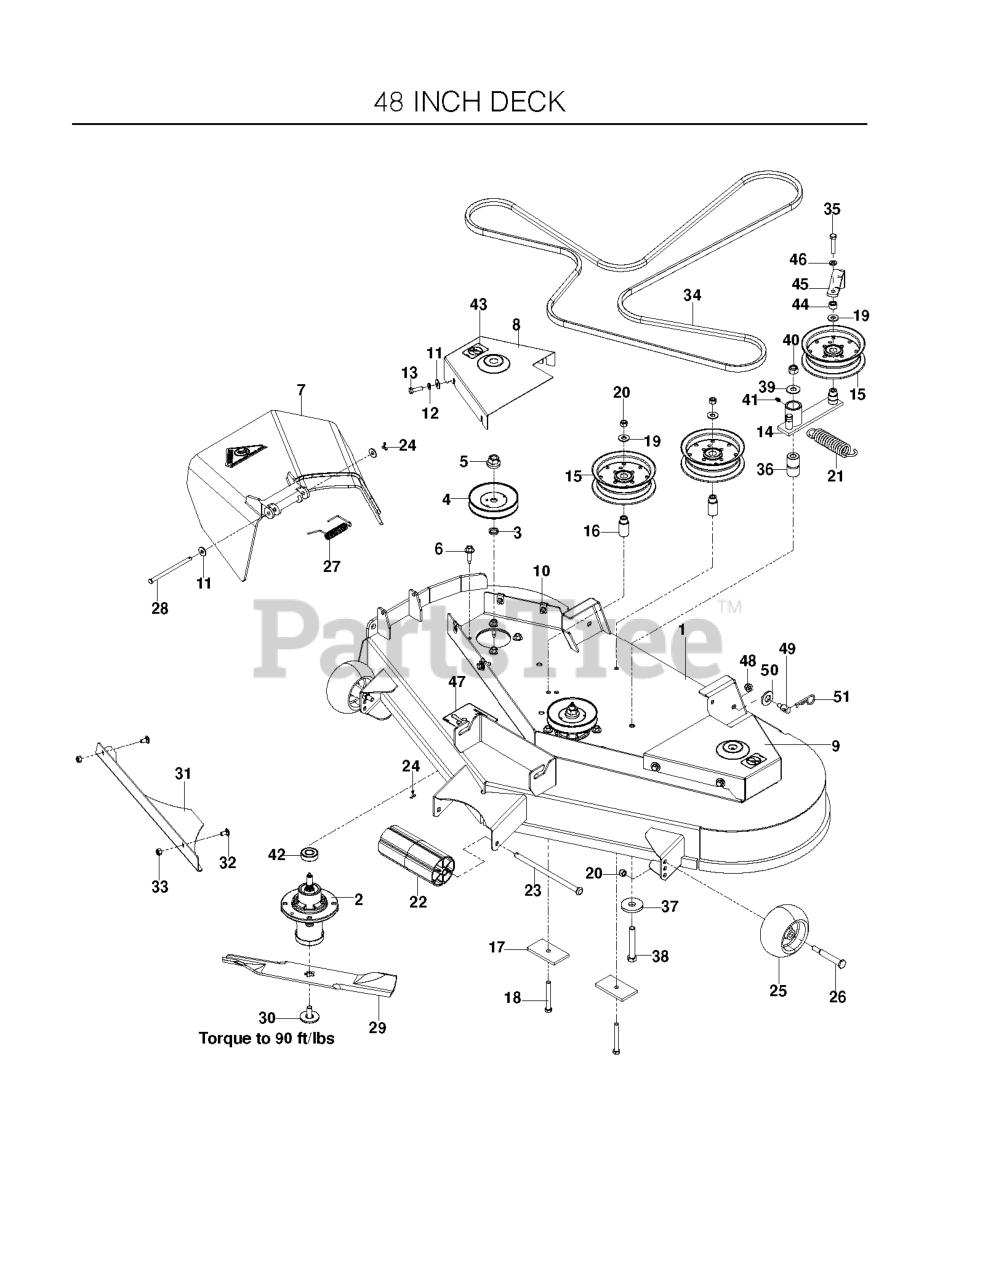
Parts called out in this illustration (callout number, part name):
1	DECK.48".TRI-FORCE.W/DECALS.OR
2	MANDREL.DECK.ASSEMBLY
3	WASHER-SPACER
4	PULLEY
5	LOCKNUT - 9/16
6	WASHER HEAD SCREW
7	DISCHARGE CHUTE 48"
8	BELT SHIELD - R.H. ORANGE
9	BELT SHIELD - L.H. ORANGE
10	U-CLIP 5/16-18 NUT RETAINER
11	WASHER 5/16 FLAT
12	WASHER.LOCK.HVY.HLCL.SPR.5/16
13	HCS 5/16C X 1
15	PULLEY, IDLER
16	IDLER BUSHING
17	SUPPORT PLATE
18	HCS 3/8C X 3
19	WASHER 3/8 FLAT
20	NUT 3/8-16 NYLOC
22	NOSE ROLLER 48"
23	NOSE ROLLER ROD
24	RP_COTTER PIN 1/8 X 3/4
25	GAUGE WHEEL
26	SHOULDER BOLT 1/2X2-5/8 ZD SPE
27	SPRING - TORSION
28	PIN-CLEVIS 5/16 DIA X 5.19 ZD
29	BLADE, 16-1/4"
30	BLADE BOLT ASSY-7/16" TB REPL
31	CONFINEMENT PLATE 48" BLK
32	CARRIAGE BOLT 5/16C X 5/8"
33	NUT 5/16 NYLOC
34	BELT, DECK
35	4CS 3/8C X 1 SERRATED HEAD
36	PIVOT BUSHING
37	WASHER, SUPPORT
38	HCS 1/2C X 3 1/4
39	WASHER 1/2 FLAT
40	NUT 1/2-13 HEX NYLOC ZD
41	ZERK
42	BEARING, BALL
43	DECAL, NO STEP
45	GUIDE, BELT
46	SLW 3/8 STD
47	DECAL, BELT ROUTING
48	5/16-18 NYLOC FLANGE NUT
49	STUD.FASTNER.W/ANTI-ROTATE
50	WASHER 5/8 FLAT
51	HAIRPIN #4
